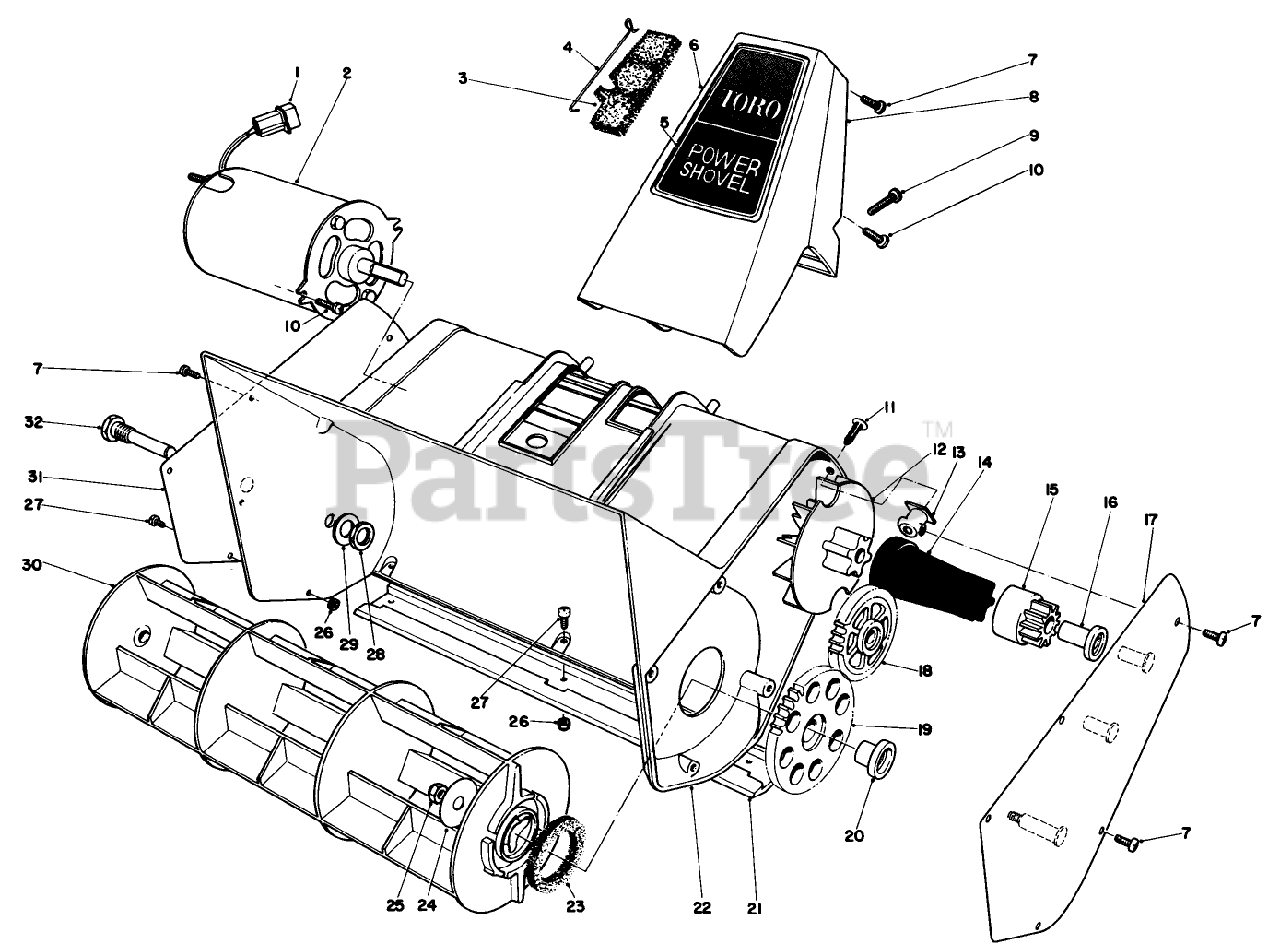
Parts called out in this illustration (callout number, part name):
3	FOAM FILTER
5	HANDLE SUPT DECAL
6	HANDLE SUPPORT, FRONT
7	SCREW-PPH
9	SCREW-PPH
10	SCREW-PPH
12	FAN, POWER SHOVEL
14	DRIVE COUPLING
15	DRIVE GEAR ASM
16	BUSHING, DRIVE GEAR
23	FELT WASHER
24	ROTOR WASHER
25	NUT-LOCK, NI
26	NUT-LOCK
27	SCREW-PPH
28	3/8 24 JAM NUT
29	WASHER-FLAT
30	ROTOR
31	RT. SIDE COVER (RAW)
32	ROTOR PIN
